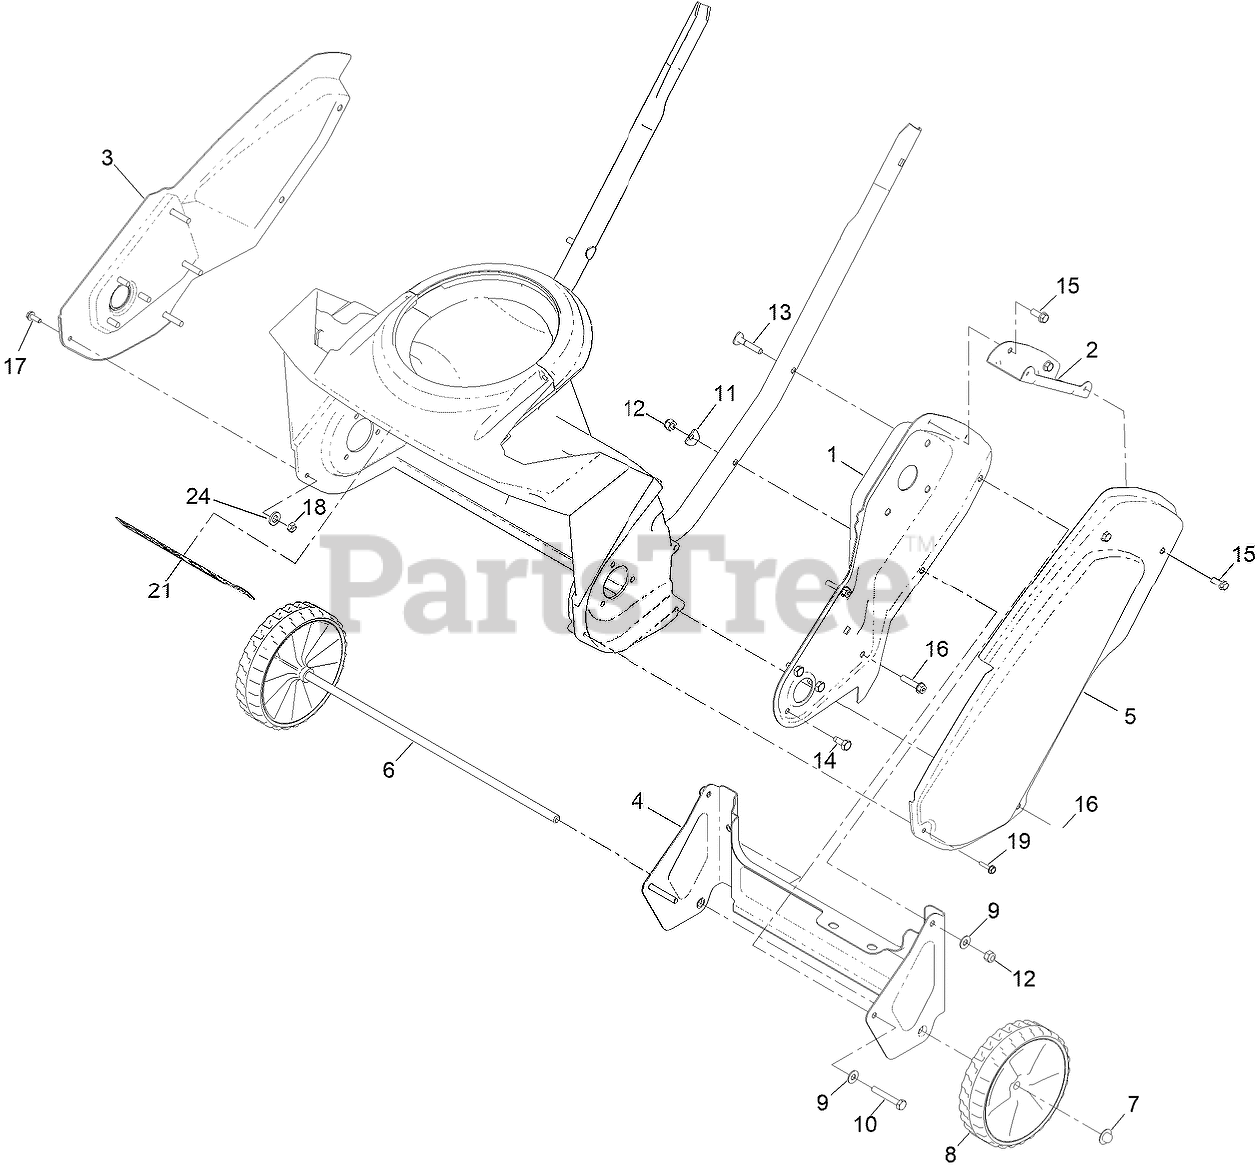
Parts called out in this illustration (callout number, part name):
1	SIDEPLATE-LH
2	BRACKET-COVER, BELT
3	SIDEPLATE-RH
4	BRACKET-WHEEL
5	COVER-BELT
7	NUT-PUSH
8	WHEEL ASM, 3/8" AXLE, 5.875 IN
9	WASHER-FLAT
10	SCREW-HH
11	WASHER
12	NUT-LOCK, NI
13	SCREW-HANDLE
14	SCREW-HH, TAPTITE
15	SCREW-HWH
16	SCREW-PLASTIC,HWH
17	SCREW-HWH
18	NUT-HEX
19	SCREW-PLASTITE, HWH
21	DECAL-FRONT
24	WASHER-PLAIN
